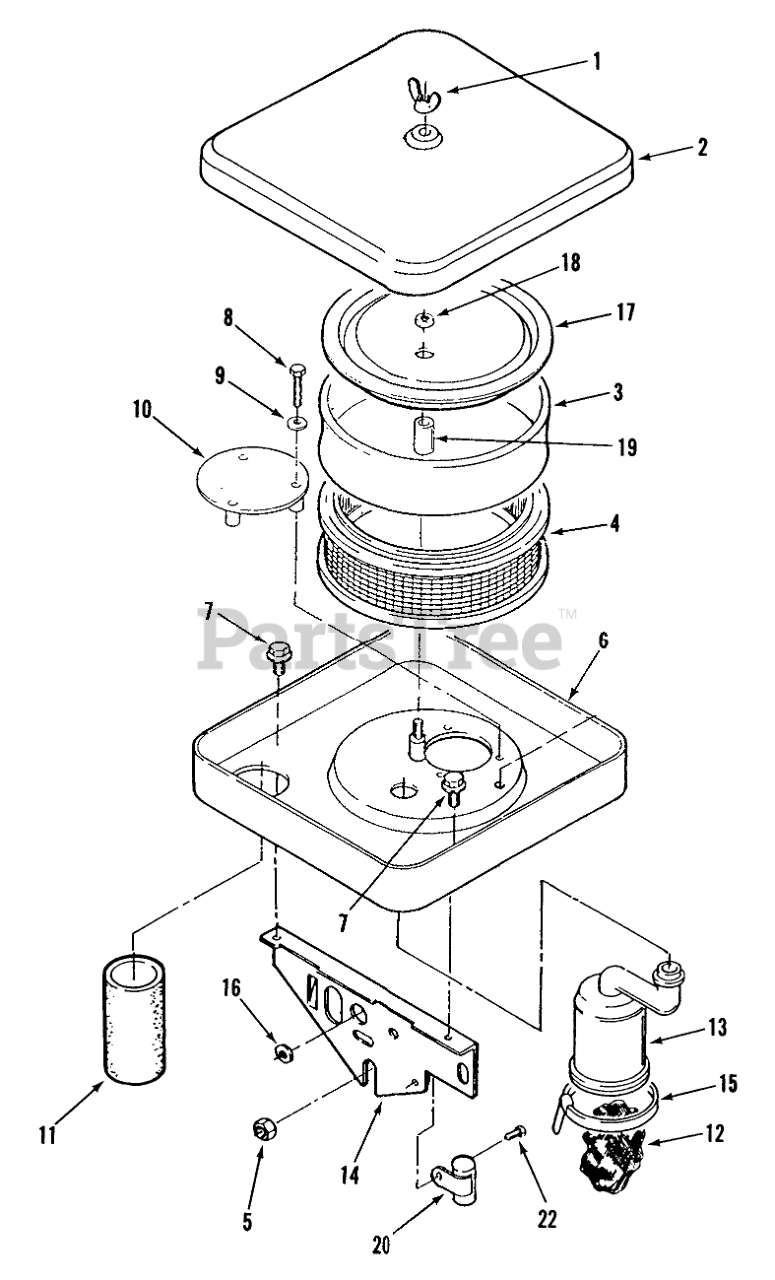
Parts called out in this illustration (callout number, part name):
1	Wing Nut 1/4-20
2	Air Cleaner Cover
3	Air Cleaner Foam Element
4	Air Cleaner Element
5	Hex Washer Hd. Flange Nut 5/16-18
6	Air Cleaner Housing
7	Wash. Hd. Screw 1/4-20 x 3/8
8	Hex. Hd. Mach. Screw No. 10-32 x 1-1/2
9	Flat Washer No. 10
10	Air Deflector Plate
11	Air Intake Tube
12	Breather Tube Filter
13	Crankcase Breather
14	Air Cleaner Support
15	Breather Tube Clamp
16	Rubber Grommet-3/4" Hole
17	Element Cover
18	Hex Nut 1/4-20
19	Air Cleaner Stud Spacer
20	Capacitor (300 VD)
21	Hex Washer Hd. Screw No. 10-32 x 5/8
